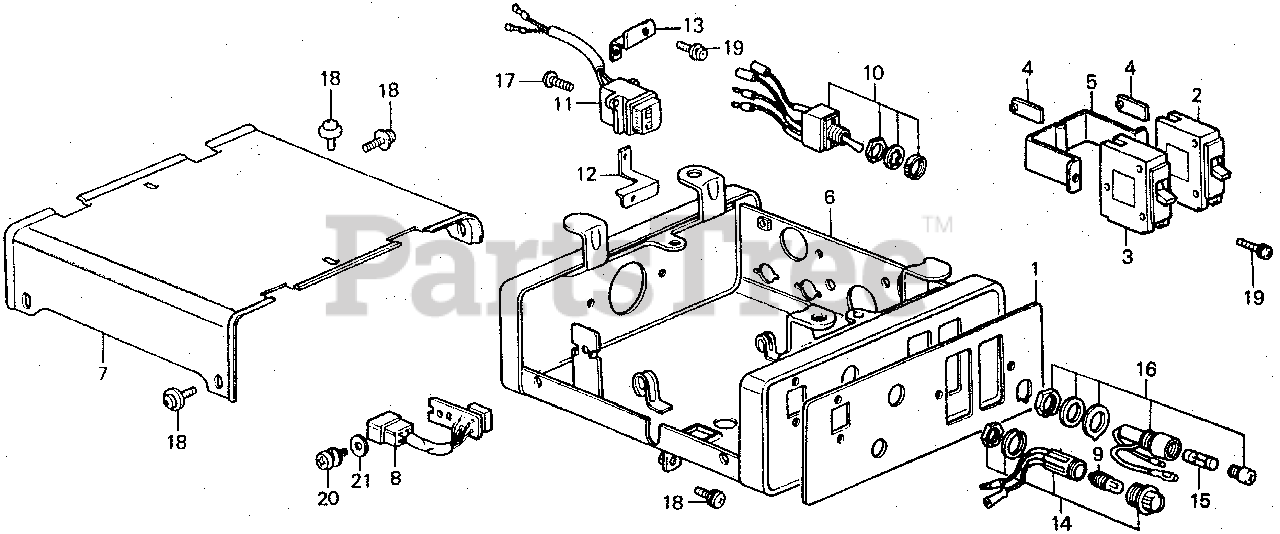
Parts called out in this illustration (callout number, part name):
1	MARK, CONTROL BOX PANEL
2	BREAKER, CIRCUIT (33A) (NOT AVAILABLE)
3	BREAKER, CIRCUIT (16.5A) (NOT AVAILABLE)
4	TERMINAL, BREAKER
5	SUPPORT, BREAKER (NOT AVAILABLE)
6	BOX, CONTROL *R8* (BRIGHT RED)
7	COVER, BOX (UPPER) *R8* (BRIGHT RED)
8	STACK ASSY., DIODE
9	BULB (24V2W)
10	SWITCH ASSY., ENGINE (NOT AVAILABLE)
11	METER, FREQUENCY
12	HOLDER A, FREQUENCY METER
13	HOLDER B, FREQUENCY METER
14	SOCKET ASSY., PILOT LAMP
15	FUSE (15A)
16	HOLDER, FUSE (NOT AVAILABLE)
17	SCREW, PAN (3X8)
18	SCREW-WASHER (5X12)
19	SCREW-WASHER (4X12)
20	SCREW-WASHER (6X12)
21	WASHER, PLAIN (6MM)
